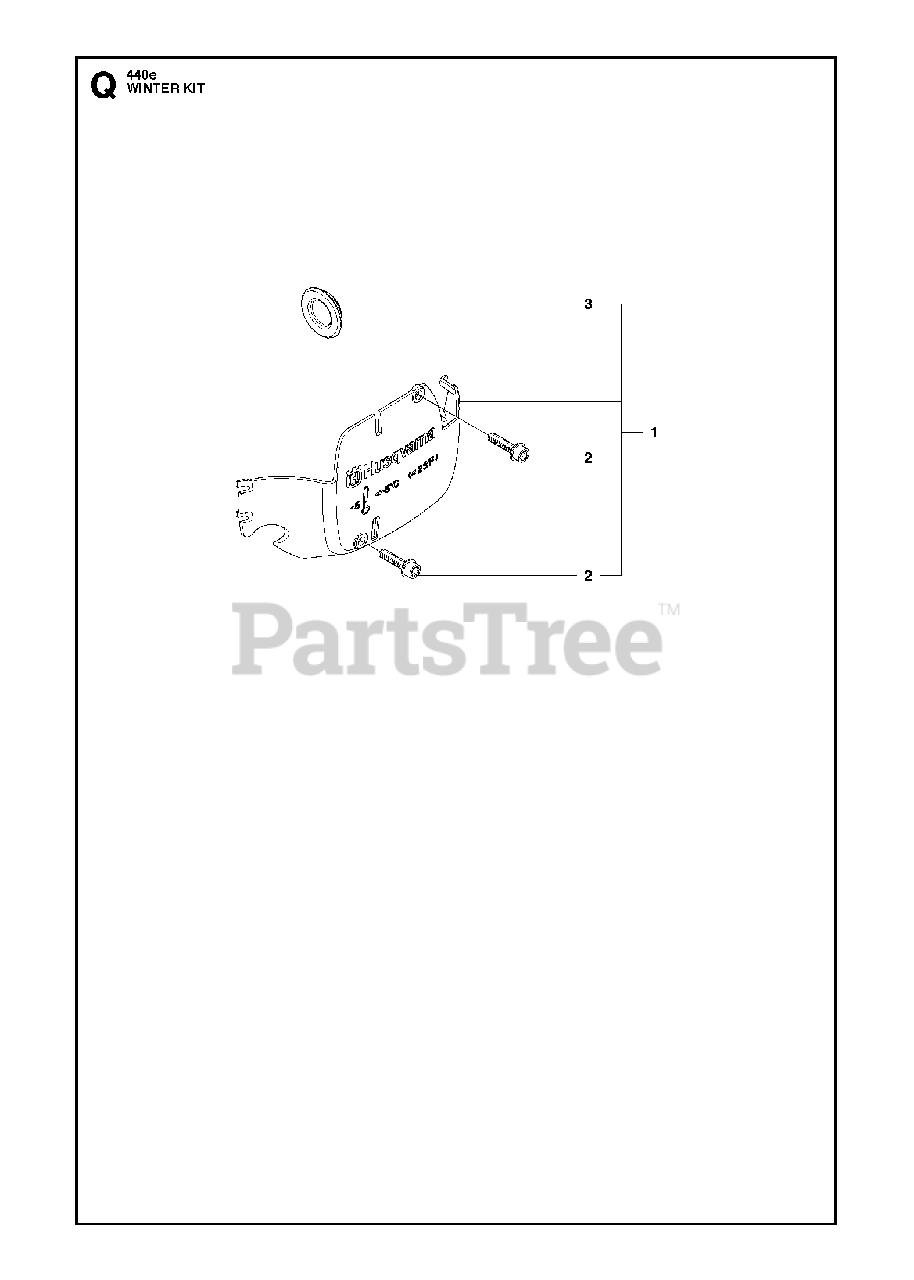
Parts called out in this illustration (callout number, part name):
1	WINTER KIT
2	SCREW
3	PLUG
